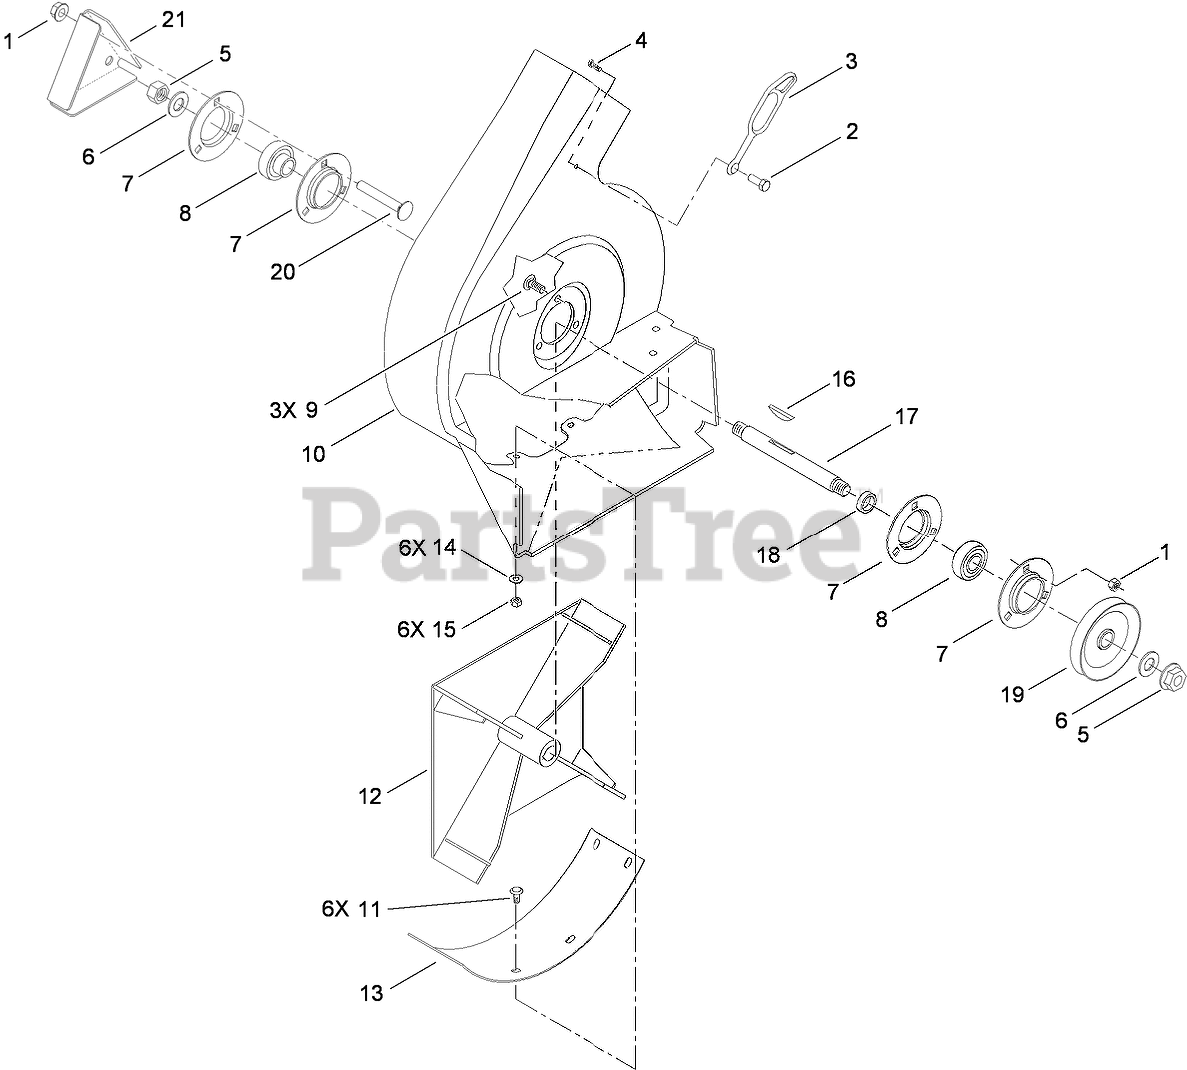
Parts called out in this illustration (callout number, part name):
1	NUT-HF
2	FASTENER-PANEL
3	RETAINER-DUCT
4	SPACER-INTERLOCK
5	NUT-JAM
6	WASHER-LOCK
7	FLANGE
8	BEARING-BALL
9	SCREW-CARR
10	HOUSING-BLOWER
11	SCREW-CARRIAGE
12	IMPELLER ASM
13	Cover-Blower, Bottom
14	WASHER-FLAT
15	NUT-LOCK, NI
17	SHAFT-BLOWER
18	Spacer
19	PULLEY-BLOWER
20	Screw-CARR
